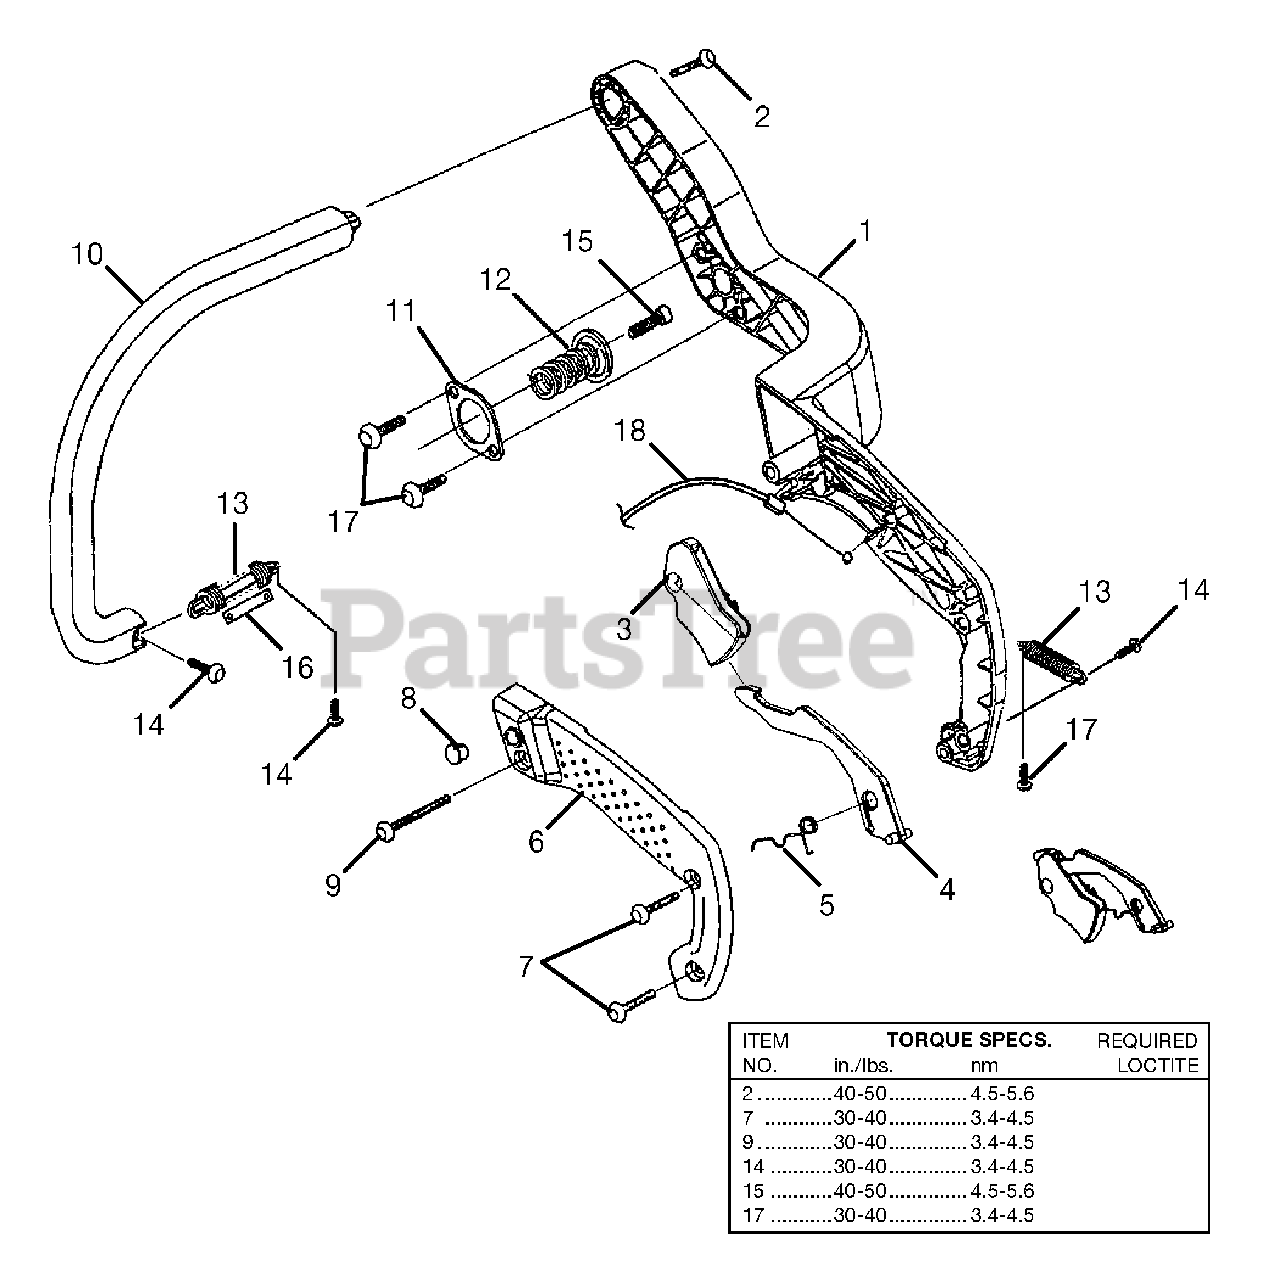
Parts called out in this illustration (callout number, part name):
1	REAR HANDLE
2	SCREW (12-14 x 1-1/2 in.)
3	TRIGGER, THROTTLE
4	THROTTLE LOCK OUT
5	TORSION SPRING
6	HANDLE COVER
7	SCREW (10-14 x 3/4 in.)
8	PLUG-PLASTIC
9	SCREW (10-14 x 1-3/8 in.)
10	FRONT HANDLE
11	ISOLATOR PLATE
12	UPPER ISOLATION SPRING
13	SPRING - ISOLATOR
14	SCREW (10-14 x 5/8 in.)
15	SCREW (10-24 x 5/8 in.)
16	SPRING RETAINER
17	SCREW (10-14 x 1/2 in.)
18	THROTTLE CABLE
